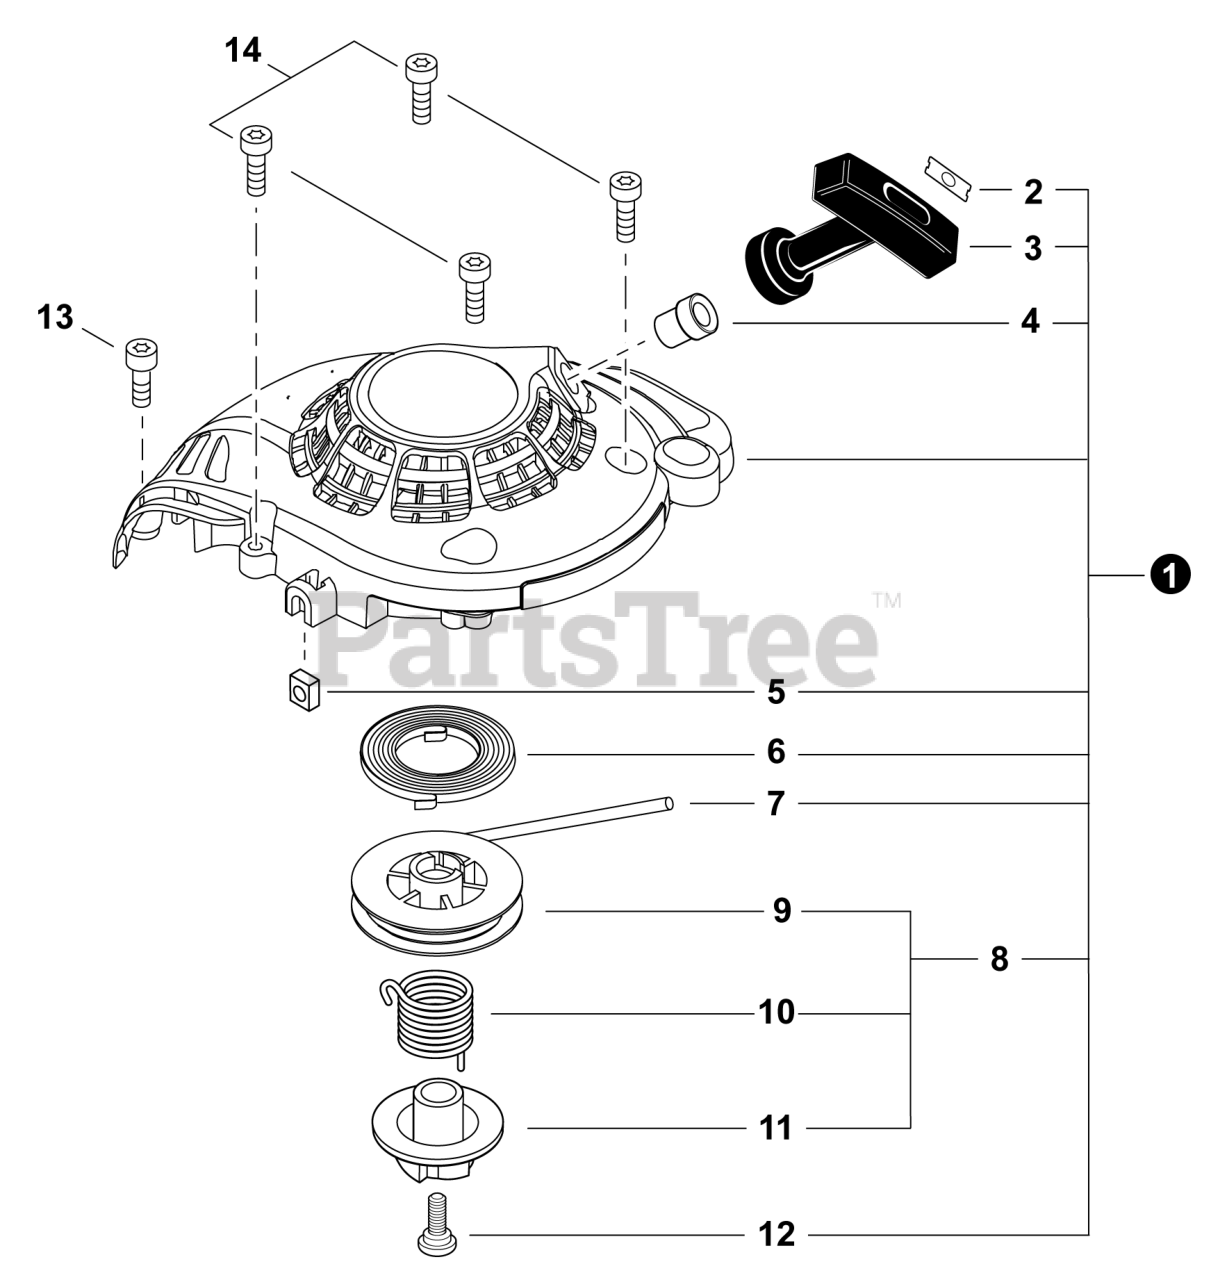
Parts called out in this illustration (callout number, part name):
1	STARTER ASSY, RECOIL
2	RETAINER, ROPE
3	GRIP, STARTER
4	GUIDE, ROPE
5	NUT - 5 - SQUARE
6	SPRING, RECOIL
7	ROPE, STARTER
8	REEL/CAM PLATE SET
9	REEL, ROPE
10	SPRING, TORSION
11	PLATE, CAM
12	SCREW 5
13	BOLT, TORX 4x16
14	BOLT, TORX 4x16
